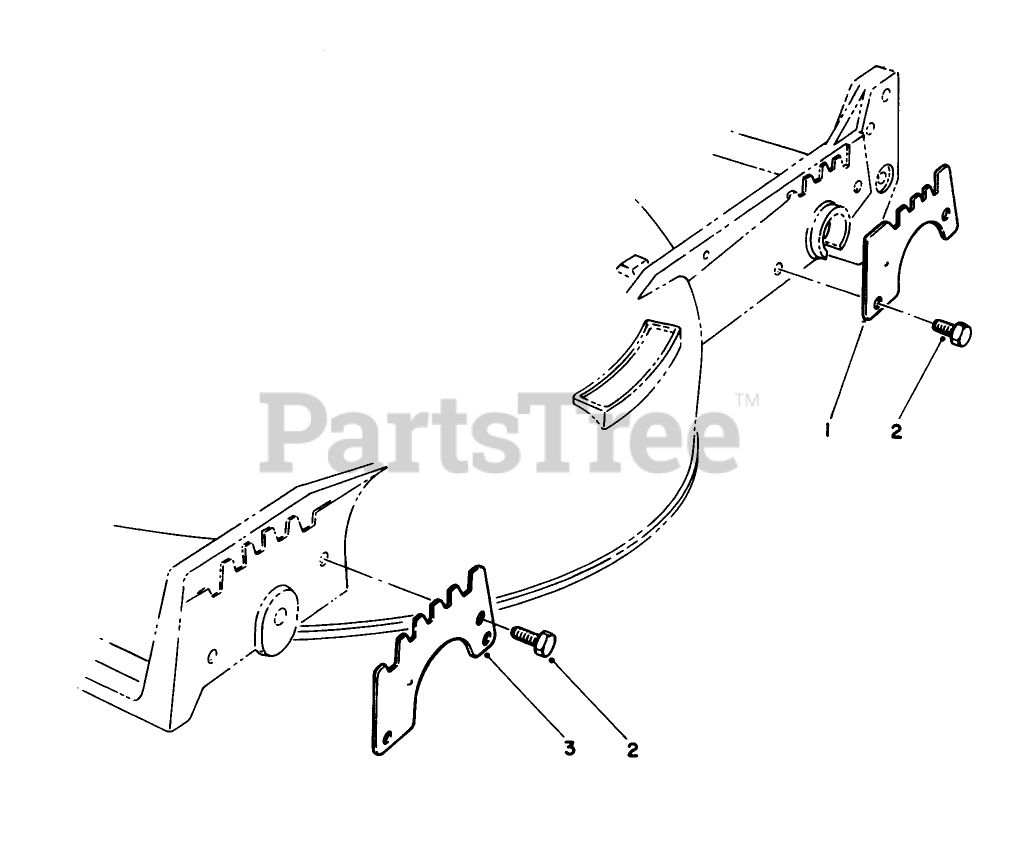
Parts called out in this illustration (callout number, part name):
1	WEAR PLATE,REAR
2	SCREW-HWH
3	Plate-Wear Front
